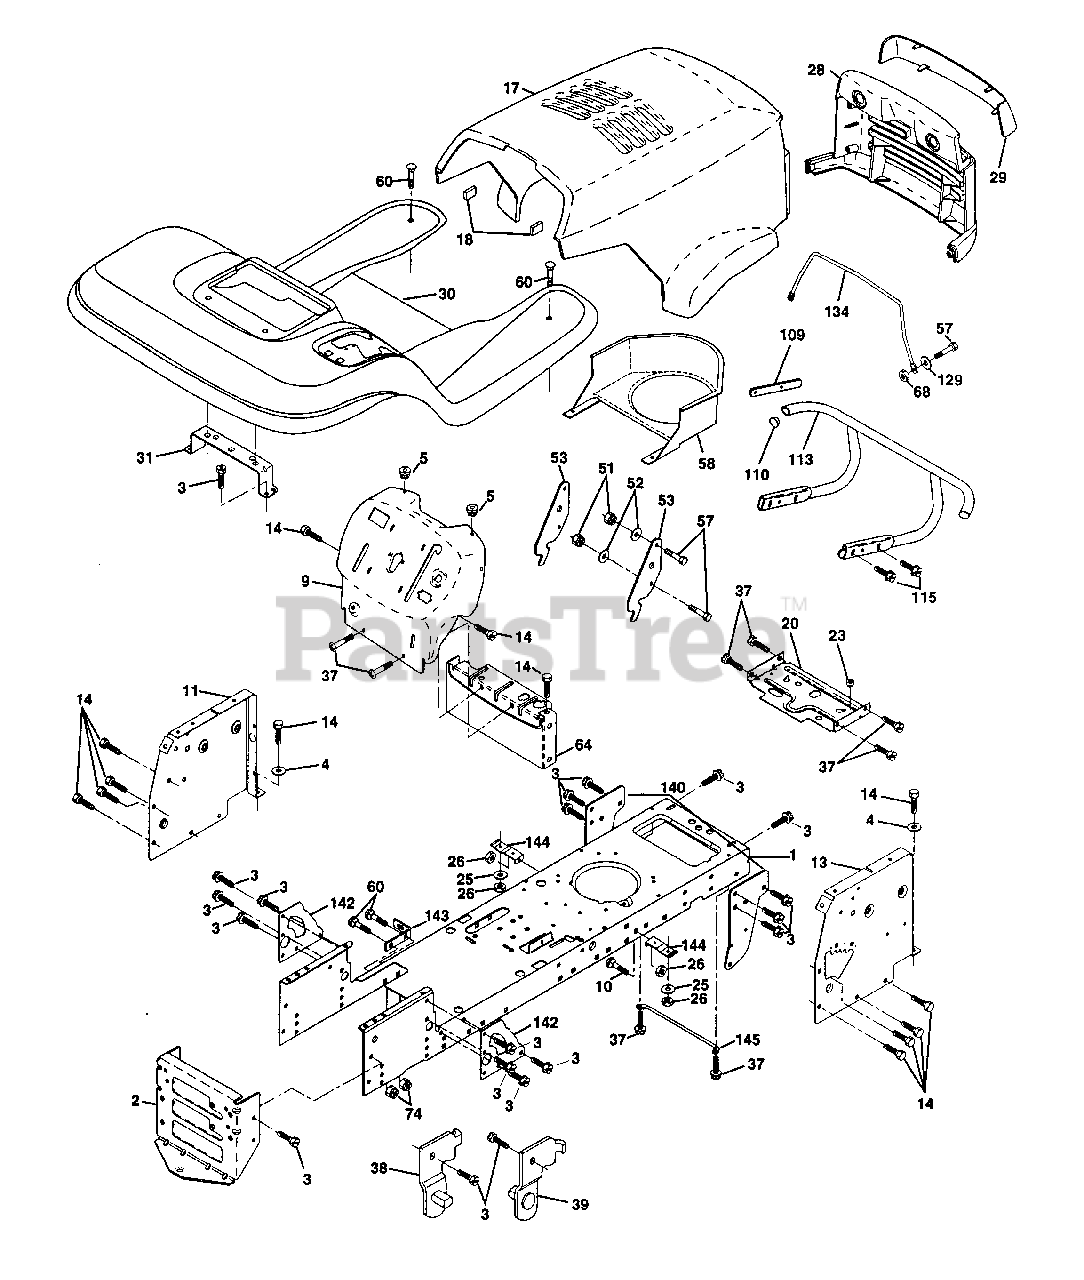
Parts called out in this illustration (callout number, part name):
1	Chassis STL Stamping 98
2	Drawbar, Stretch
3	Screw Thdrol 3/8-16x3/4 Ty-tt
4	Washer 13/32 x 3/4 x 16 Ga.
5	Bumper Hood/Dash
9	Dash P/L M, N/AMM N/HM Grey
10	Bolt Carriage 3/8-16 x 1
11	Panel Dash Lh
13	Panel Dash Rh
14	Screw Thdrol 3/8-16 x 1/2 Ty-tt
17	Hood LT/PL Husqvarna
18	Bumper Hood
20	Plate Mtg Battery Fuel Tank Fr
25	Washer 13/32 X 13/16 X 12 Ga
26	Nut Lock Hex W/Ins 3/8-16 Unc
28	Grille LT/PL Husqvarna
29	Lens LT/PL Husqvarna
30	Fender Footrest STLT Pnt
31	Bracket Support Fender
37	Screw Thdrol 6/16-18 x 1/2 TYT
38	Bracket, Asm. Pivot, L.H., Mower Rear
39	Bracket, Asm. Pivot, R.H., Mower Rear
51	Nut Lock Hex W/Ins 1/4-20
52	Washer 9/32 x 7/8 x 16 Ga.
53	Bracket Pnt. Pick off LT/PL Husqvarna
57	Bolt Hex 1/4-20 x 3/4
58	Air Duct Engine P/L
60	Bolt Rdhd Sqnk 3/8-16unc x 3/4
64	Dash Lower STLT
68	Nut Keps Hex 1/4-20 UNC
74	Nut Crownlock 3/8-16 UNC
109	Bracket Extension Bumper
110	Plug Plastic
113	Bumper Asm.
115	Screw Thdrol 3/8-16 x 1-1/4
129	Washer 9/32 x 5/8 x 16 Ga.
134	Rod Support Hood LT/PL Husq.
140	Bracket Suspension Front
142	Plate Reinforcement STLT
143	Bracket Swaybar Chassis
144	Bracket Pnt Footrest STLT
145	Rod Pivot Chassis/Hood
